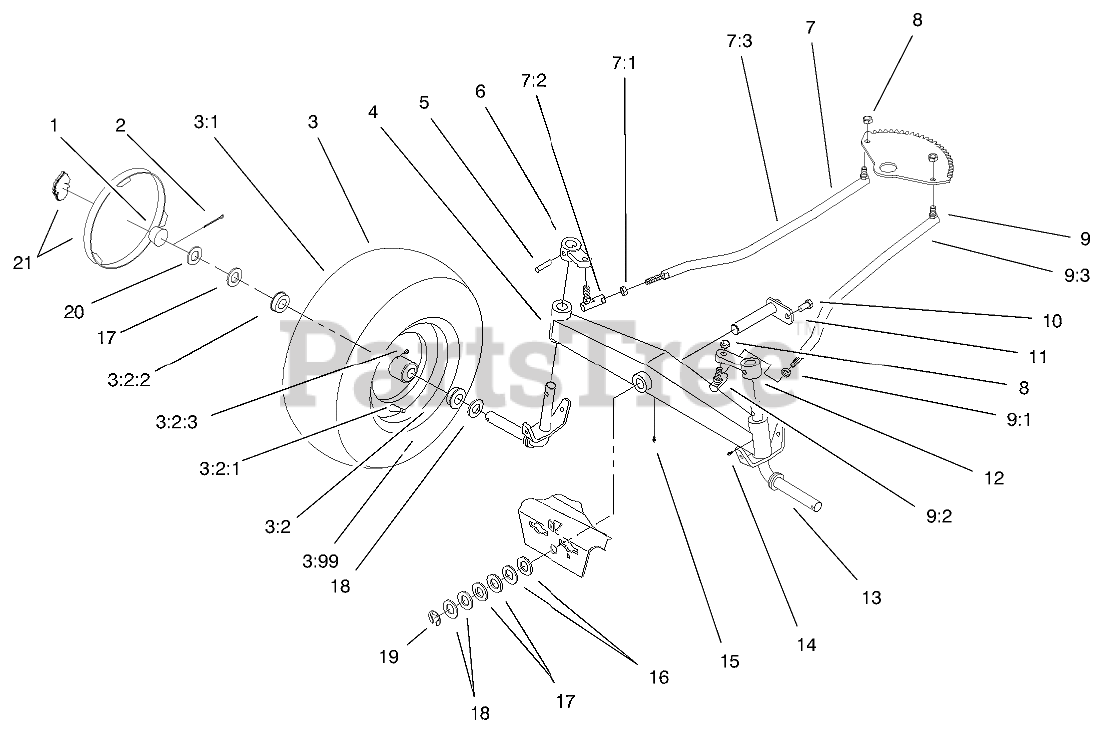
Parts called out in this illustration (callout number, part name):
1	CAP-HUB
2	PIN-COTTER
3	Wheel&tire ASM,Front
3:2	Wheel ASM
3:2:1	VALVE
3:2:2	BEARING-WHEEL
3:2:3	ZERK-GREASE
3:99	TUBE-INNER
4	AXLE-FRONT
6	Arm-Front Spindle
7	LINKAGE-STEERING, RH
7:1	NUT-JAM
7:2	BALL-JOINT
7:3	Ball Link ASM
9	LINKAGE-STEERING, LH
9:1	NUT-JAM
9:2	BALL-JOINT
9:3	Ball Link ASM
10	SCREW-HWH, TAPTITE
11	PIN-AXLE
12	Arm-Front Spindle
13	SPINDLE
14	FITTING-GREASE
15	FITTING-LUBE, 45 DEG
16	Washer
17	WASHER
18	WASHER-SHIM
19	E-RING
20	WASHER-PLAIN
21	Kit-Silver Hub Cap/Logo (Only On: 72106)
